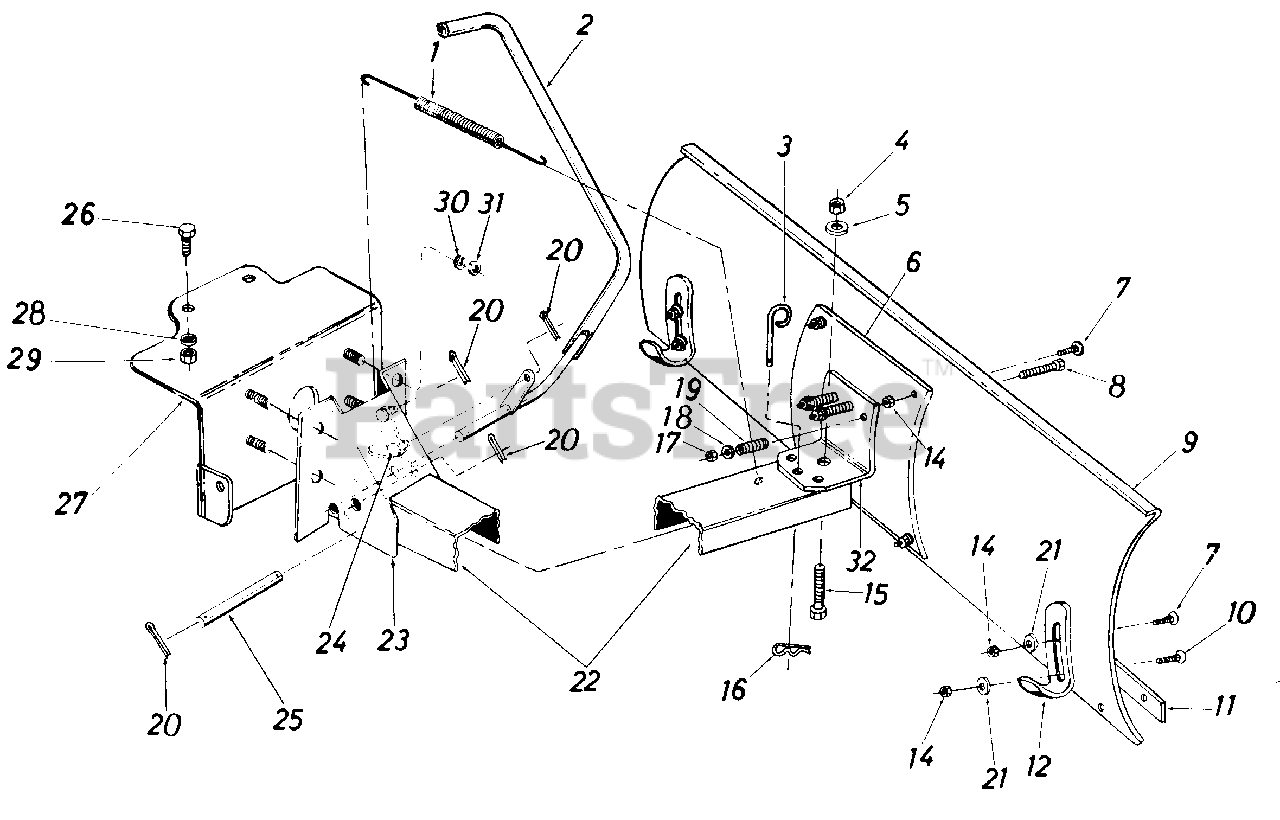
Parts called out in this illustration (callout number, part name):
1	Extension Spring
2	Lift Handle Ass'y.
3	Pivot Lock Pin
4	Hex Cent. L.-Nut 1/2-13 Thd.
5	Fl.-Wash. 17/32 I.D. x 1.25" Lg.
6	Reinforcement Plate
7	Carriage Bolt 5/16-18 x .75" Lg.*
8	Hex Scr. 3/8-16 x 3.75" Lg. Grade 5
9	42" Blade
10	Carriage Bolt 5/16-18 x 1.00" Lg.*
11	42" Wear Plate
12	Shoe Skid
14	Hex Cent. L.-Nut 5/16-18 Thd.*
15	Hex Scr. 1/2"-13 x 1.25" Lg.*
16	Hair Pin Cotter
17	Hex Cent. L.-Nut 3/8-16 Thd.
18	Fl.-Wash. 3/8" I.D.
19	Compression Spring
20	Cotter Pin 1/8" Dia. x 1.00" Lg.*
21	Fl.-Wash. 5/16" Scr.
22	Push Bar Channel
23	Pivot Support Bracket
24	Lift Link
25	Channel Pivot Shaft
26	Hex Scr. 5/16-18 x 1.00" Lg. Grade 5
27	Support Bracket Ass'y.
28	L.-Wash. 5/16" Scr.*
29	Hex Nut 5/16-18 Thd.*
30	L.-Wash. 3/8" Scr.*
31	Hex Nut 3/8-16 Thd.
32	Support Bracket
